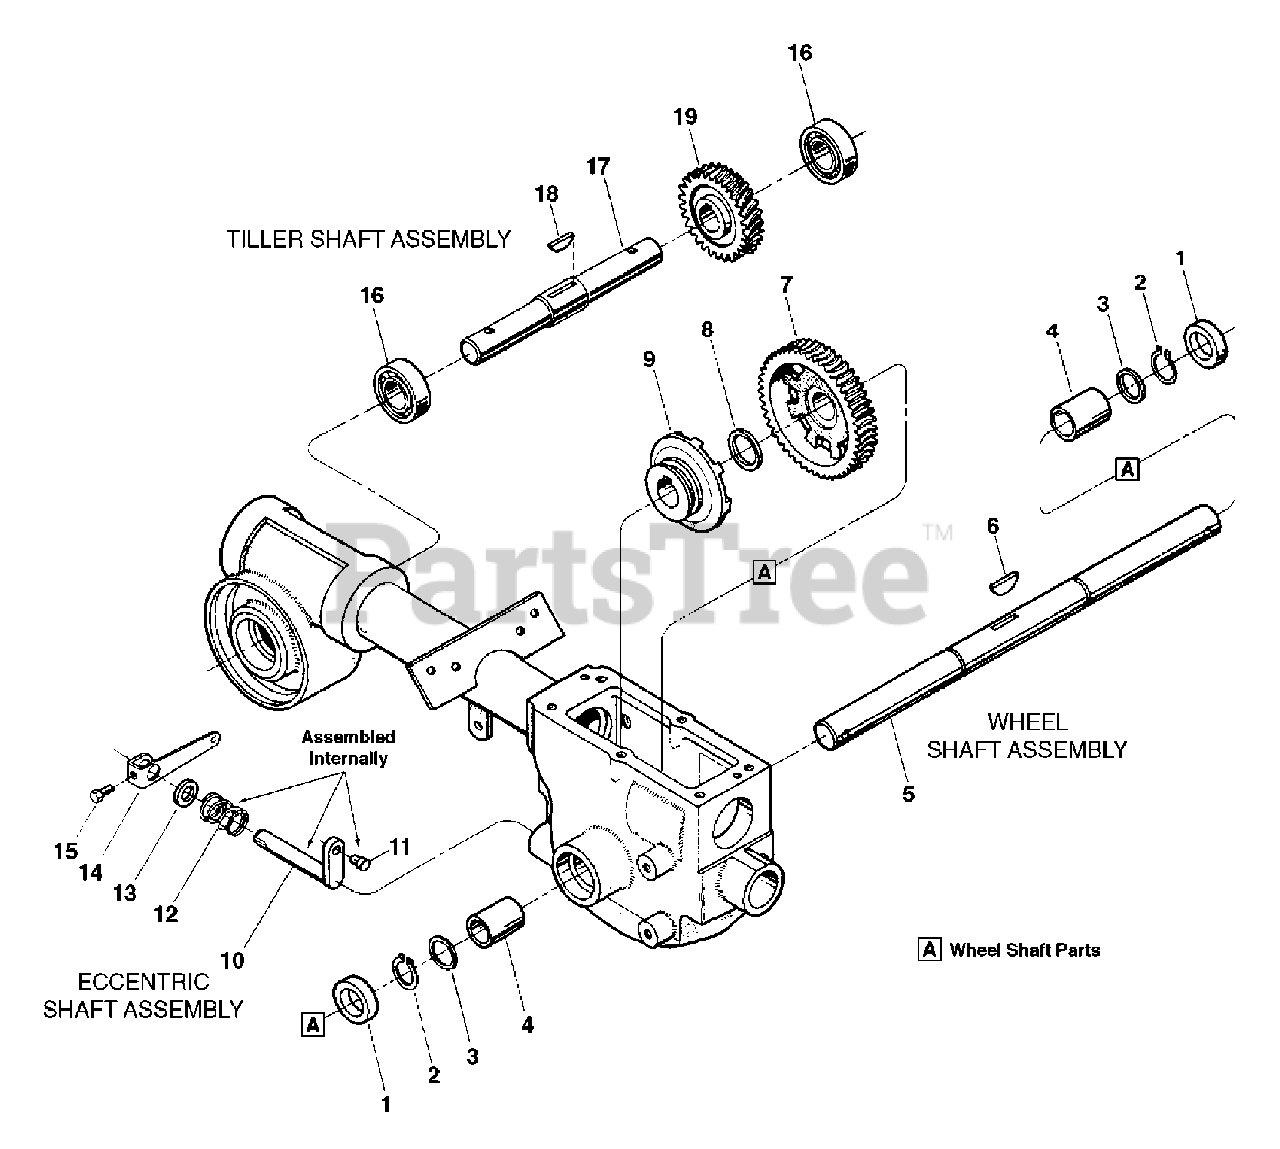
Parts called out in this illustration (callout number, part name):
1	Oil Seal
2	Retaining Ring (heavy-duty, external)
3	Shim, 1-1/64 I.D. .062" thick
4	Bushing
5	Wheel Shaft
6	Hi-Pro Key, 1/4 x 1-5/16
7	Wheel Drive Worm Gear (cast-iron)
8	Shim (between key and gear), 1.016 I.D. x 1.468 O.D. x .062 Thick
9	Wheel Drive Clutch (cast-iron)
10	Eccentric Shaft
11	Pin, Eccentric Shaft
12	Spring
13	Oil Seal
14	Eccentric Shaft Lever
15	Hex Hd. Screw, 1/4-20 x 1/2
16	Ball Bearing
17	Tiller Shaft
18	Woodruff Key, 1/4 x 1-1/4
19	Tiller Drive Worm Gear (bronze)
